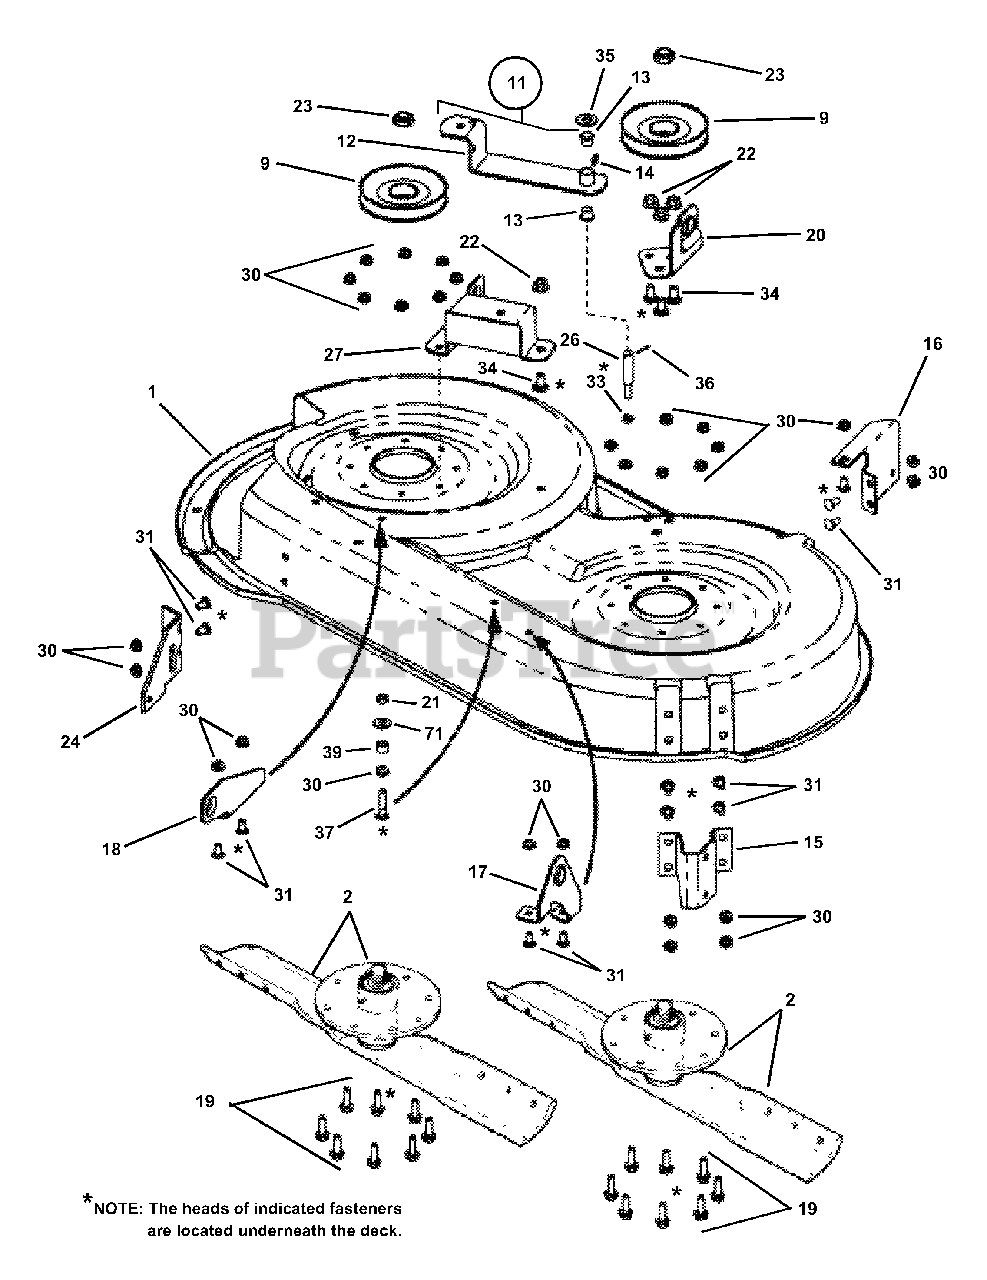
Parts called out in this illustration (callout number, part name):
1	DECK, 38" Replacement
2	ASSEMBLY, Spindle
9	PULLEY, 4-1/2" O.D., A/B Groove
11	ASS'Y, Idler Arm
12	WELDMENT, Idler Arm
13	BUSHING, 1/2" Nylon
14	LUBE FITTING, Straight (press-fit for .187 dia. Hole)
15	BRACKET, Gage Wheel
16	BRACKET, Left Hand Wheel
17	BRK'T, 38" Deck Lift, LH Front
18	BRK'T, 38" Deck Lift, RH Front
19	SCREW, 5/16-18 x 1" Hex Head Cap, Grade 5
20	BRK'T, Left Hand Rear Lift Arm
21	NUT, 5/16-18 Hex Center Lock Grade 5
22	NUT, 3/8-16 Hex Flange Lock
23	NUT, 5/8-18 Hex Nyloc
24	BRACKET, Gage Wheel
26	STUD, Idler (5/16-24 thread)
27	BRACKET, Stationary Idler
30	NUT, 5/16-18 Hex Flange Lock, Grade 5
31	BOLT, 5/16-18 x 5/8" Short Neck Carriage, Grade 5
33	NUT, 5/16-24 Hex Center Lock
34	BOLT, 3/8-16 x 3/4" Short Neck Carriage, Grade 5
35	WASHER, 1/2" x 1-1/16" Flat
36	COTTER-PIN, 3/32 x 3/4"
37	BOLT, 5/16-18 x 1-1/2" Short Neck Carriage, Grade 5
39	SPACER, .340 I.D. x .630 O.D. x .310 Thick
71	WASHER, 3/8" I.D. x 7/8 O.D. Flat
